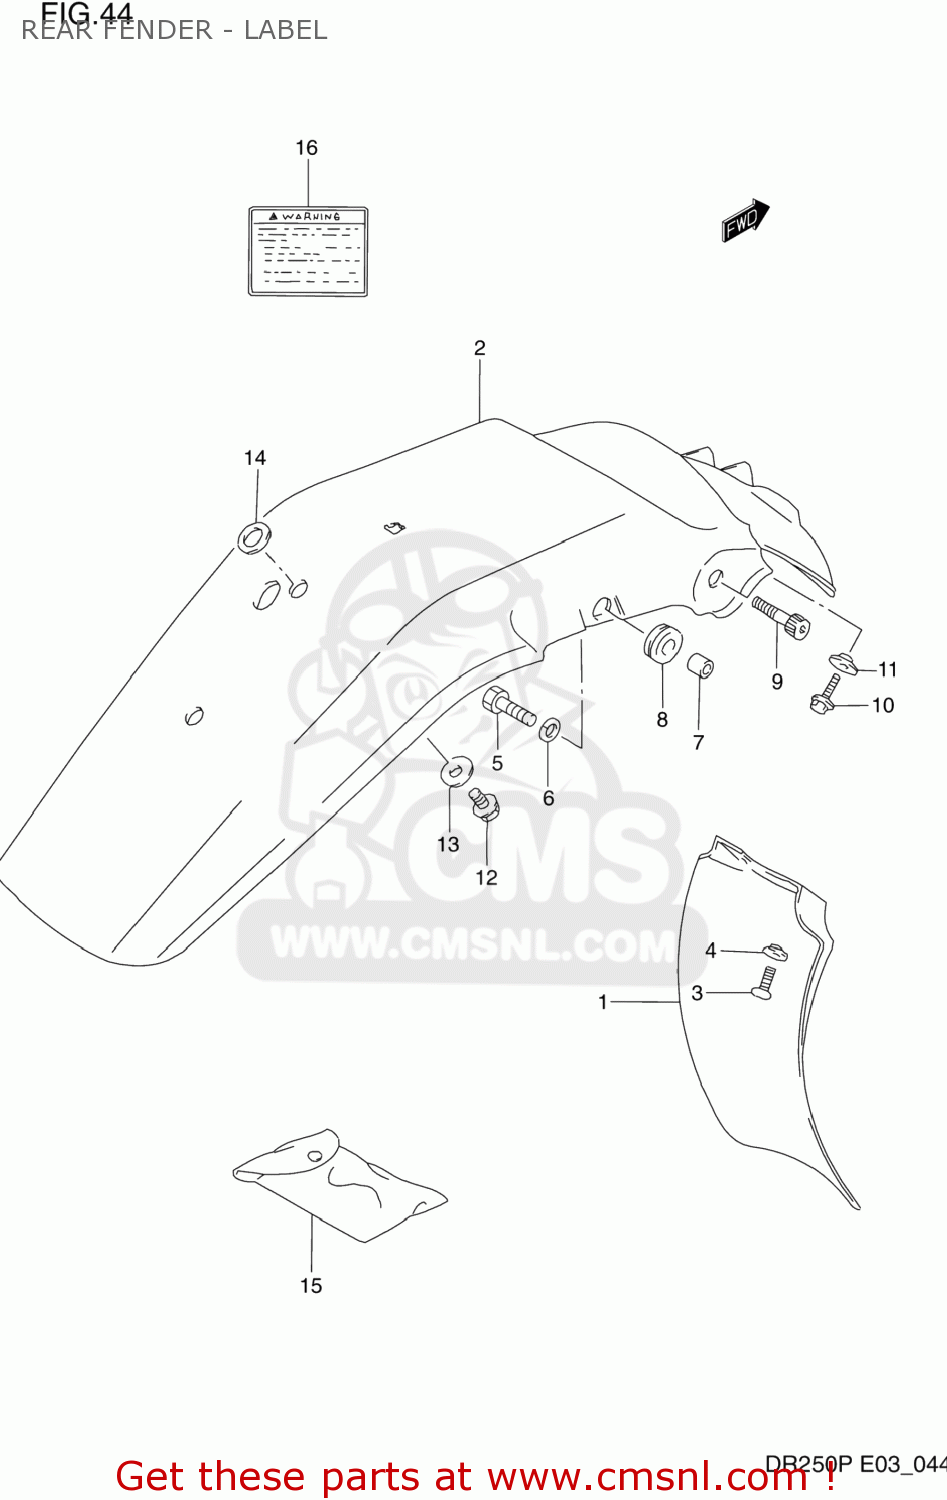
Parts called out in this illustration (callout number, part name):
1	BODY,RR FENDER FR
2	FENDER,REAR
3	SCREW 6X12
4	WASHER
5	BOLT
6	LOCK WASHER
7	SPACER (8.8X12X7)
8	CUSHION
9	BOLT(8X30)
10	BOLT 6X16
11	WASHER
12	BOLT
13	WASHER
14	WASHER(14.2X26X1.2)
15	TOOL ASSY
16	LABEL
